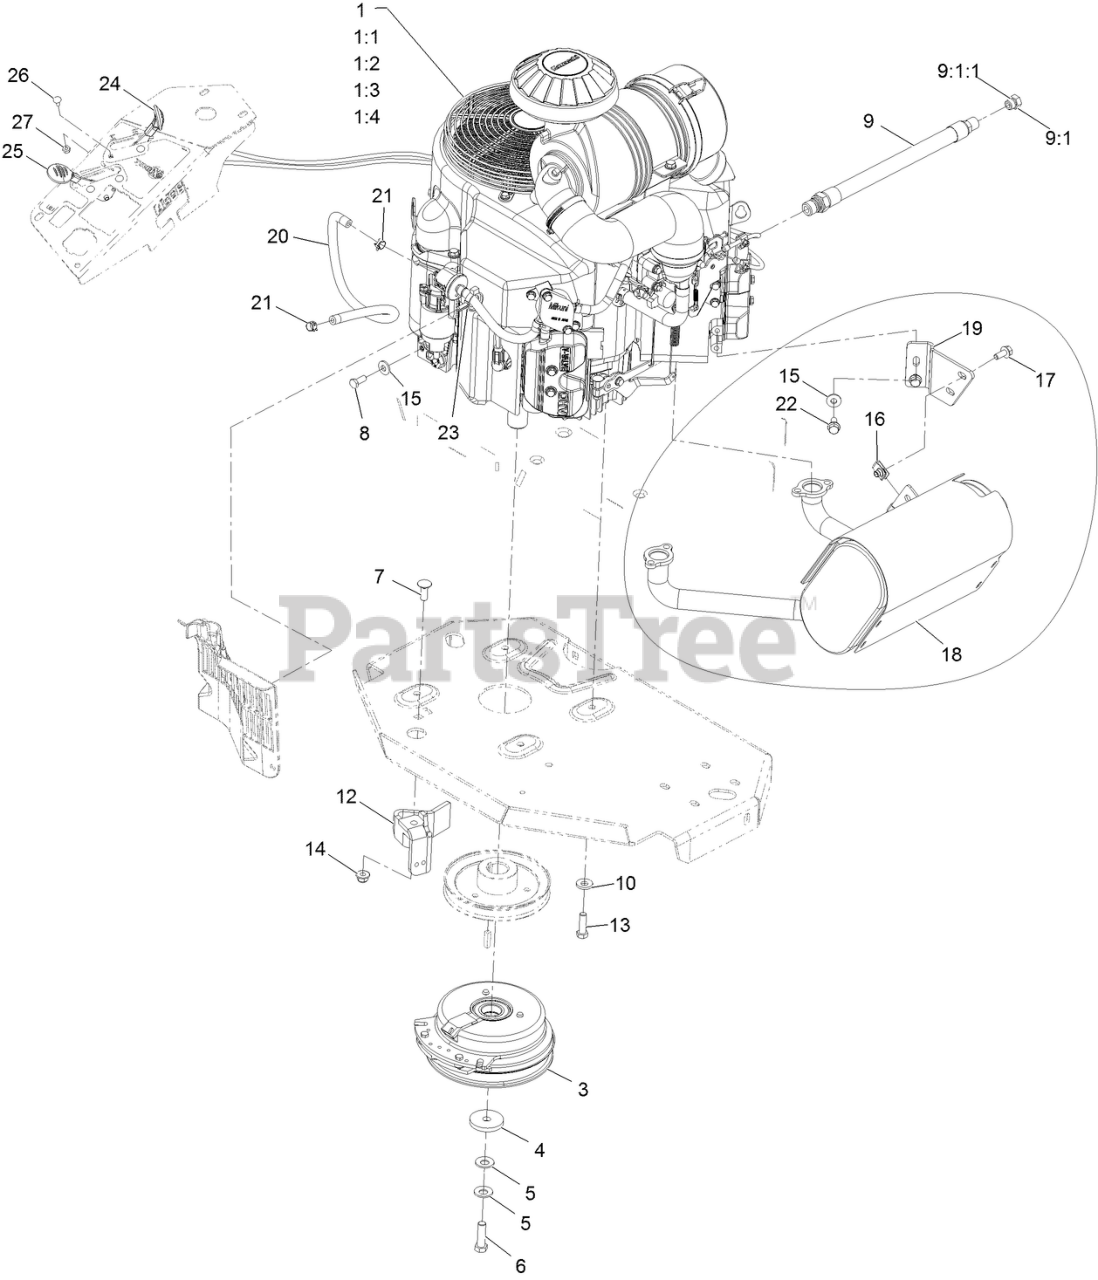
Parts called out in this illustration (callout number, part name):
1:1	Kawasaki 49065-2078 Engine Oil Filter
1:2	Kawasaki 49019-0031 Fuel Filter
1:3	Kawasaki 11013-7039 Safety Filter
1:4	Kawasaki 11013-7038 Air Filter
3	CLUTCH KIT
4	WASHER-CLUTCH
5	WASHER-SPRING
6	SCREW-HH 7/16-20 X 1 1/2 W/LOCTITE
7	SCREW-CARR
8	SCREW-HH
9	ENGINE OIL DRAIN HOSE ASM
9:1	PLUG-HH
9:1:1	O-RING
10	WASHER-BELLEVILLE
12	CLUTCH-ANCHOR
13	SCREW-HH
14	NUT-HF, NI
15	WASHER-SPRING
17	SCREW-HHF
18	KIT, MUFFLER
19	BRACKET-MUFFLER
20	HOSE-FUEL
21	CLAMP-HOSE
22	SCREW-HHF
23	CLAMP-HOSE
24	ASM, CHOKE CABLE
25	ASM,THROTTLE CABLE
26	BOLT-CARR
27	NUT-LOCK, NI
